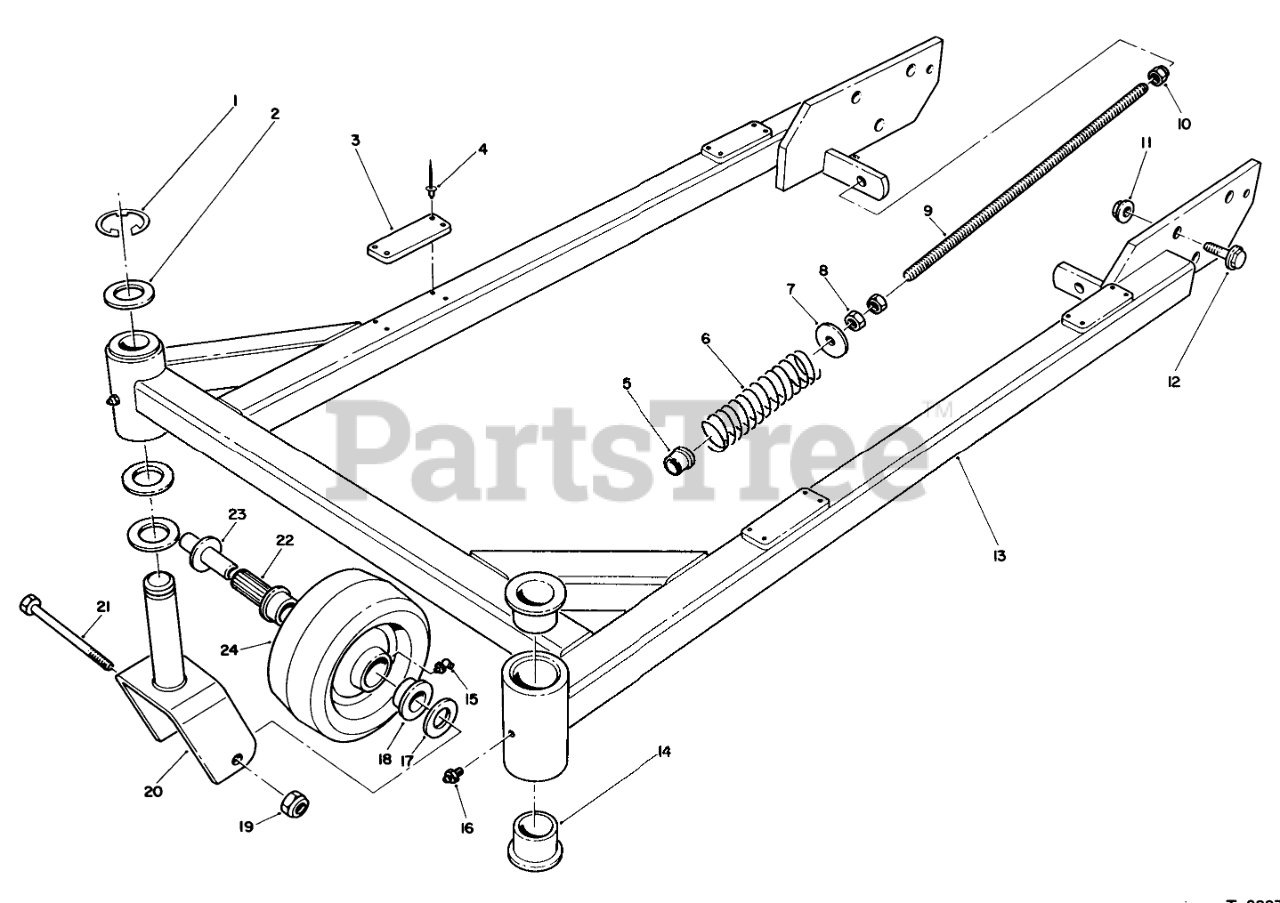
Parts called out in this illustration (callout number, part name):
1	RING-RETAINING
2	WASHER-THRUST
3	PAD-RUBBER
4	NUT-LOCK, NI
5	BUSHING-FLANGE
6	SPRING
7	WASHER
8	NUT-JAM
9	SHAFT-ADJUSTING
10	WASHER-FLAT
11	NUT-LOCK, FLANGE
12	SCREW-HHF
13	Carrier Frame Assembly (Incl. Ref. #14)
14	Bushing
15	FITTING-LUBE, 45 DEG
16	FITTING-GREASE
17	SPACER-WHEEL
18	BEARING-OUTSIDE
19	NUT-HEX
20	Fork-Castor
21	SCREW-HH
22	BEARING-ROLLER
23	SPANNER
24	Wheel Assembly-Castor (Incl. Ref. #15, 18, & 22)
